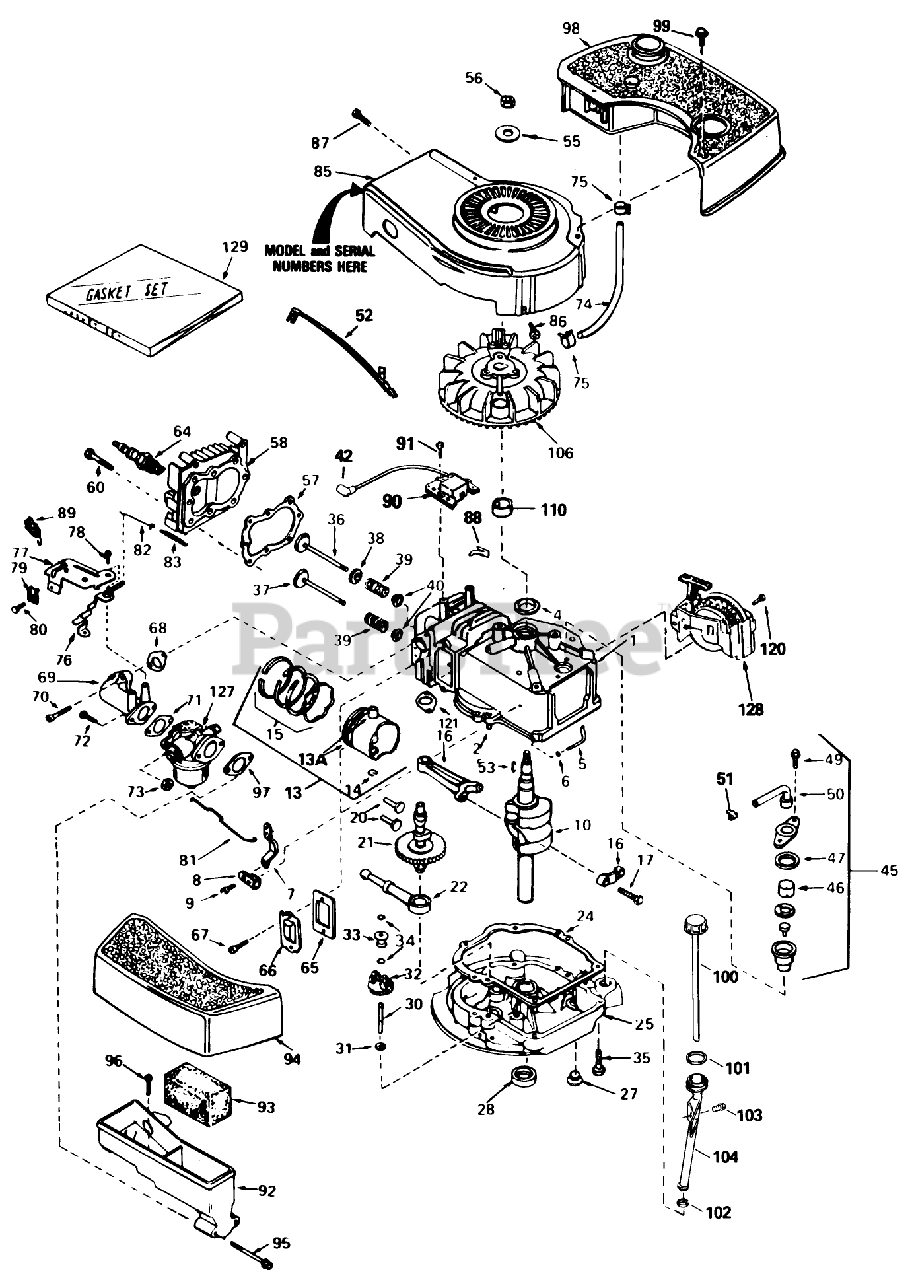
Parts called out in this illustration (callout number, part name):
1	Cylinder Assy. (Inc. #2 4)
2	Pin-Dowel
4	Seal-Oil
5	Rod, Governor (Incl. No. 36)
6	Washer-Flat
7	Governor Lever
8	Clamp-Lever, Governor
9	Screw
10	Crankshaft
13	Piston-Pin Ring Assy. (Std.)(Incl. Ref. #16A, 17 18)
13	Piston-Pin Ring Assembly (.010 oversize)(Incl. Ref. #16A, 17 18)
13	Piston, Pin Ring Assy. (.020 Oversize)(Incl. Ref. #13A, 14, 15)
13A	Piston Pin Assy. (Std.)(Incl. Ref. #14)
13A	Piston Pin Assembly (.010 oversize)(Incl. Ref. #18)
13A	Piston Pin Assy. (.020 Oversize) (Incl. Ref. #14)
14	Ring-Retaining, Piston Pin
15	Ring Set-Piston (Std.)
15	Ring Set, Piston(.0100versize)
15	Ring Set (.020" OS)
16	Rod Assy., Connecting (Incl. Ref. #17)
17	Bolt-Rod, Connecting
20	Lifter-Valve
21	Camshaft(Mech.Comp. Release)
22	Oil Pump ASM
24	Gasket
25	Flange Assy.-Mounting (Incl. Ref. #26, 27, 28 31)
27	Plug Oil Drain
28	Seal Oil
30	Shaft-Governor
31	Washer-Flat
32	Governor Gear ASM
33	Spool-Governor
34	Ring-Retaining
35	Screw (1/4-20 x 1-1/4)
36	Valve, Intake (Std.) (Incl. Ref. #40)
36	Valve, Intake (1/32" oversize)(Incl. No. 40)
37	Valve, Exhaust (Std.)(Incl. No. 40)
37	Valve, Intake (1/32" oversize)(Incl. No. 40)
38	Seal Assy., Intake
39	Spring-Valve
40	Cap-Valve, Spring
42	Cover-Spark Plug
45	Breather Assy. (Incl. Ref. #46 thru 51)
46	Element-Breather
47	Gasket-Breather
49	Screw (10-24 x 9/16)
50	Tube, Breaker
51	Clip, Breather
52	Wire-Ground
53	Key-Flywheel
55	Washer-Belleville
56	Nut-Flywheel
57	63573 GIL 42 SNWTHW
58	Head-Cylinder
60	Screw (5/16-18x1-1/2)
64	Spark Plug-Resistor (R J19 L M)
65	Gasket-Breather
66	Cover-Valve
67	Screw
68	Gasket-Intake
69	Pipe, Intake (Incl. No. 68)
70	Screw (1/4-20 x 1)
71	Gasket-Carburetor
73	Nut and Lock Washer (1/4-28)
74	Line-Fuel
75	Clamp-Line, Fuel
76	Lever Control
77	Control Assy., Speed (Incl. Nos, 76, 78 89)
78	Screw, Hex Washer Hd Shoulder Self-Tap
79	Conduit
80	Screw (10-32 x 3/8)
81	Link-Throttle
82	Link Governor Spring
83	Spring Governor
85	Housing-Blower
86	Screw (1/4-20x19/32)
87	Screw (10-24 x 9/16)
88	Clip-Wire
89	Terminal
90	Solid State
91	Screw
92	Body Air Cleaner
93	Filer, Air
94	Cove, Air Cleaner
95	Screw Fil Hd.
96	Screw, Hex Washer Hd Shoulder Self-Tap
97	Gasket-Air Cleaner
98	Tank-Fuel
99	Screw (10-32 x 35/64)
100	Dipstick, Oil
101	O-Ring
102	Gasket
103	Screw (10-32 x 1/2)
104	Tube, Oil Fill
106	Flywheel
110	Spacer
120	Screw (1/2-20x5/8)
121	Gasket Exhaust
127	Carburetor (Incl. Ref. #71)
128	Starter-Sidemount
129	Gasket Set
